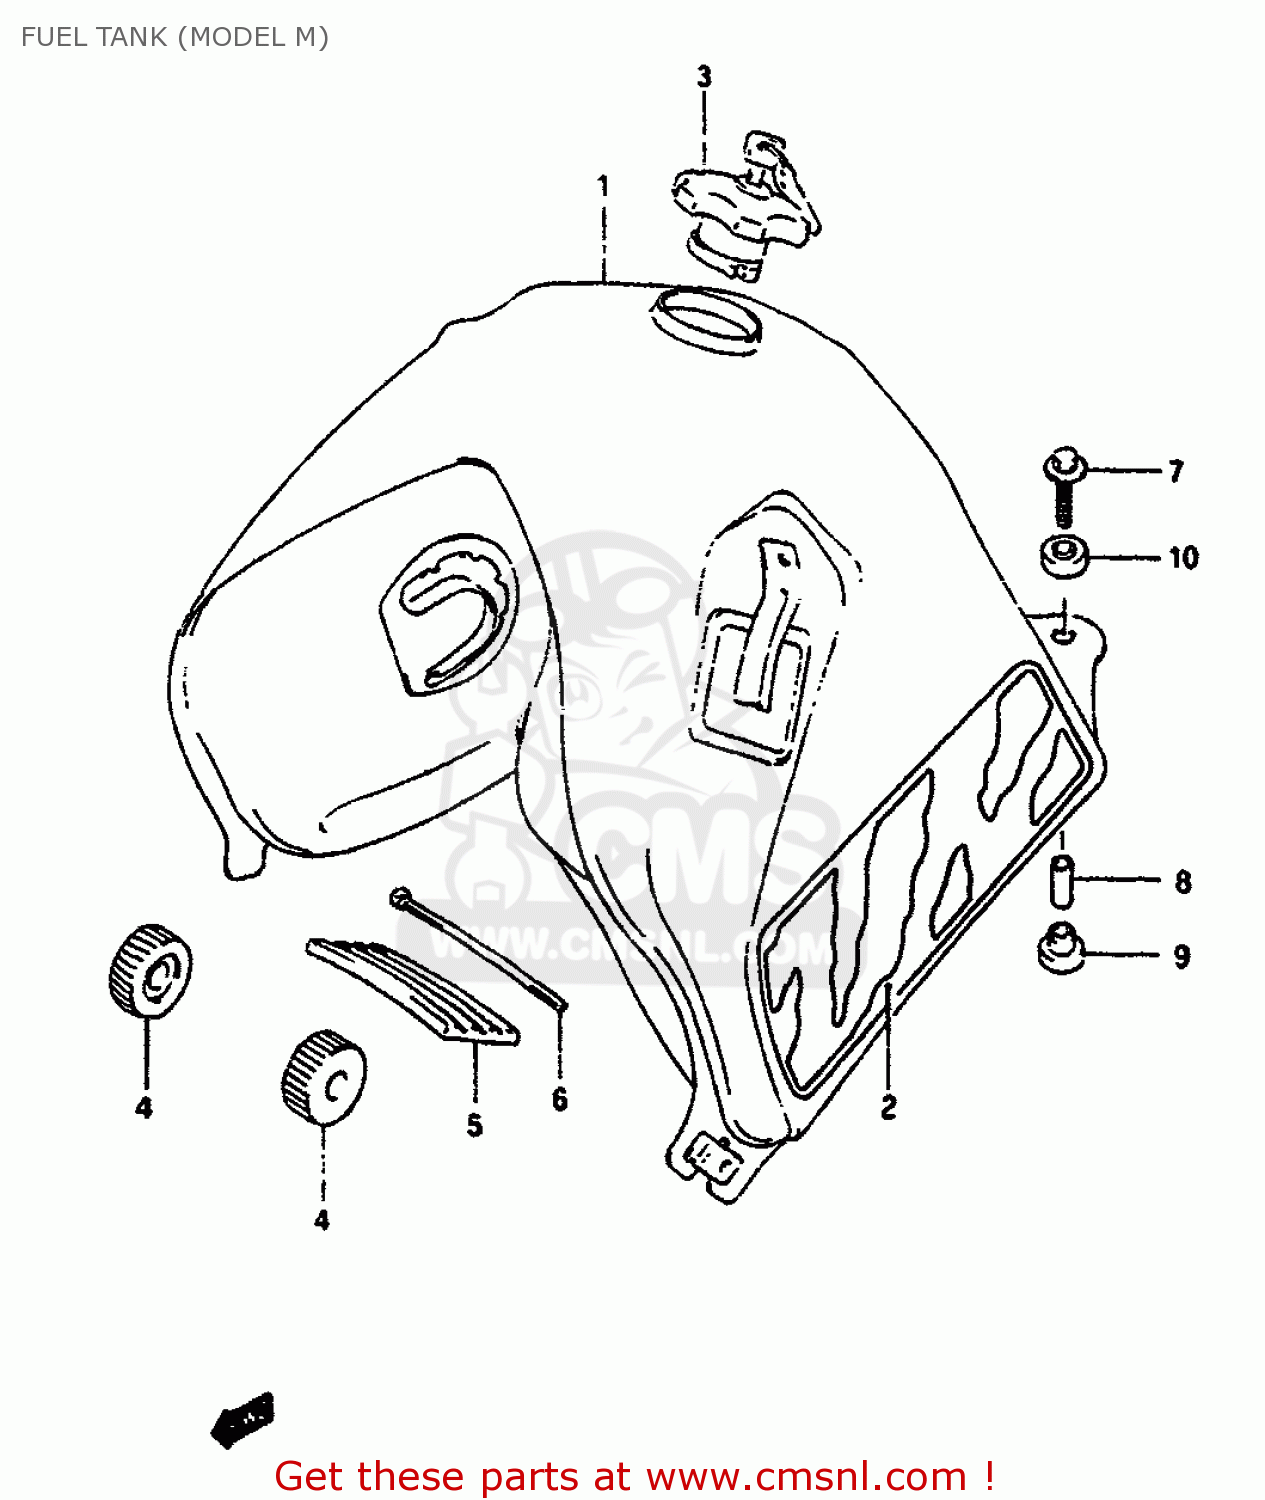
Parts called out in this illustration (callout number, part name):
1	TANK ASSY,FUEL (RED)
2	TAPE SET,FUEL TANK
3	CAP SET,FUEL TANK
4	CUSHION,FUEL TANK FR
5	CUSHION
6	CLAMP
7	BOLT
8	SPACER
9	CUSHION
10	CUSHION
